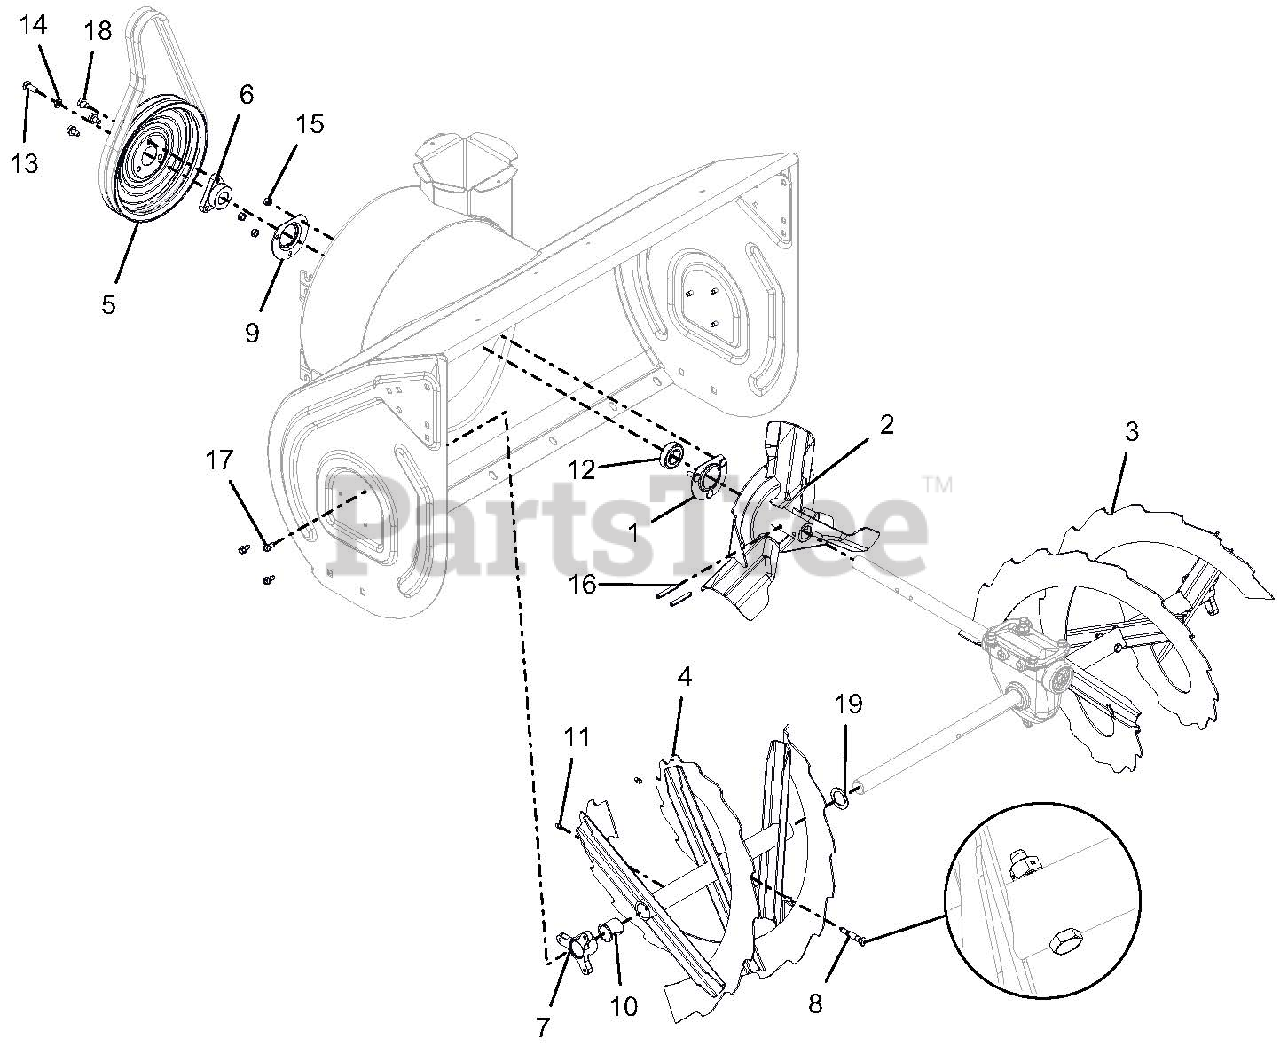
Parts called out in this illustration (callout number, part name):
1	BEARING FLANGE
2	IMPELLER, 3 BLADE-14"
3	RAKE, LH-32"(1 ID X 15.75 OD)
4	RAKE, RH-32"(1 ID X 15.75 OD)
5	PULLEY, SPIN FORM DUAL GROOVE
6	PULLEY HUB, D-BORE .87 PRO
7	BUSHING, RAKE SHAFT 1"
8	SHEAR BOLT SERVICE ASSEMBLY
9	BEARING FLANGE
10	BSHG-FLG SPLIT NYLINER 1.0" HP
11	ZERK,FITTING .25X.125 DRIVE IN
12	BRG-BALL .876X1.75X.50 RSTFP
13	BLT-HEX .31-24X.75 YWZC GR5
14	WSHR-LK .312X.097 HVY YWZC
15	@NUT-LK-CTR .25-20 YWZC
16	PIN-ROLL .250X1.75
17	SCR-TAP .25-20X.50 HWH TR YWZ
18	@SCR-TAP .31-18X.50 HWH TR YWZ
19	WSHR-FL-STL 1.010X1.505X.062YZ
